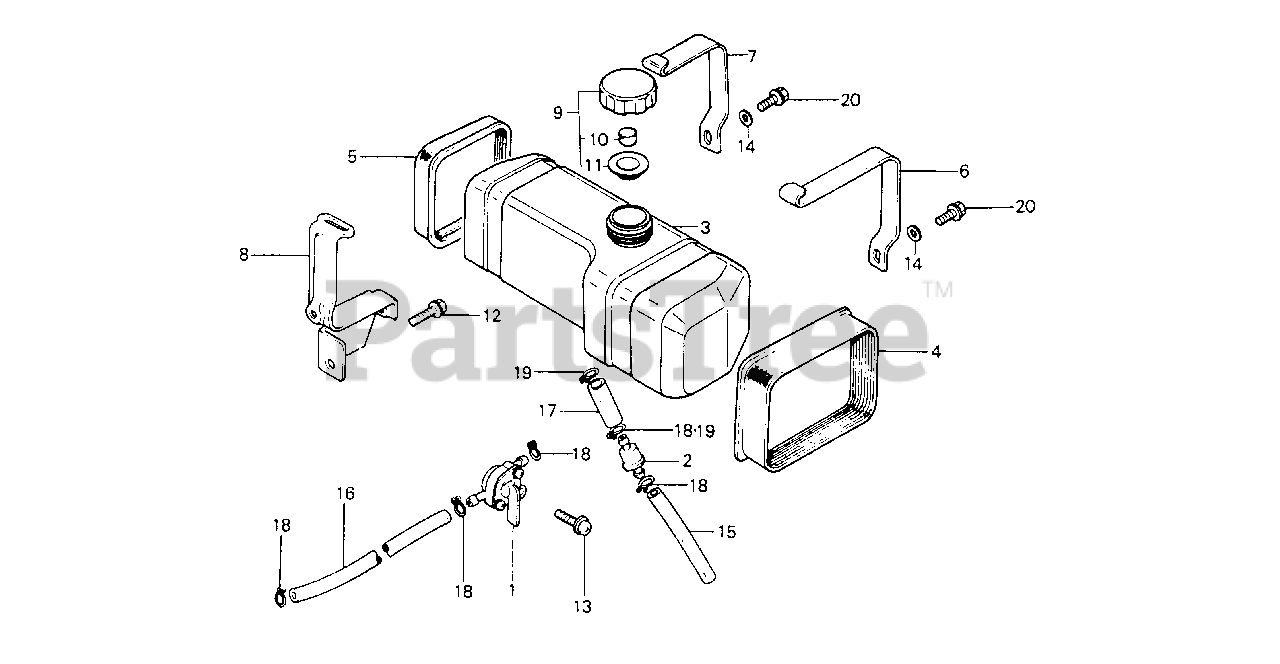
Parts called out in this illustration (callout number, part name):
1	PETCOCK ASSY. (NOT AVAILABLE)
2	FILTER, FUEL
3	TANK, FUEL (NOT AVAILABLE)
4	RUBBER A, FUEL TANK MOUNTING (NOT AVAILABLE)
5	RUBBER B, FUEL TANK MOUNTING (NOT AVAILABLE)
6	BAND A, TANK MOUNTING (NOT AVAILABLE)
7	BAND B, TANK MOUNTING (NOT AVAILABLE)
8	STAY B, TANK
9	CAP ASSY., FUEL TANK
10	SPONGE, FUEL CAP BREATHER
11	GASKET, FUEL CAP
11	GASKET, FUEL CAP (NOT AVAILABLE)
12	BOLT, FLANGE (6X12) (CT200)
13	SCREW-WASHER (5X12)
14	WASHER, PLAIN (6MM)
15	BULK HOSE, FUEL (4.5X3000) (95001-450(95001-45001-60M)
15	BULK HOSE, FUEL (4.5X3000) (4.5X115)
16	BULK HOSE, FUEL (4.5X3000) (4.5X195)
17	TUBE, FUEL (NOT AVAILABLE)
17	BULK HOSE, FUEL (5.5X3000) (5.3X40)
18	CLIP, TUBE (B8)
19	CLIP, TUBE (B10)
20	BOLT, FLANGE (6X12)
